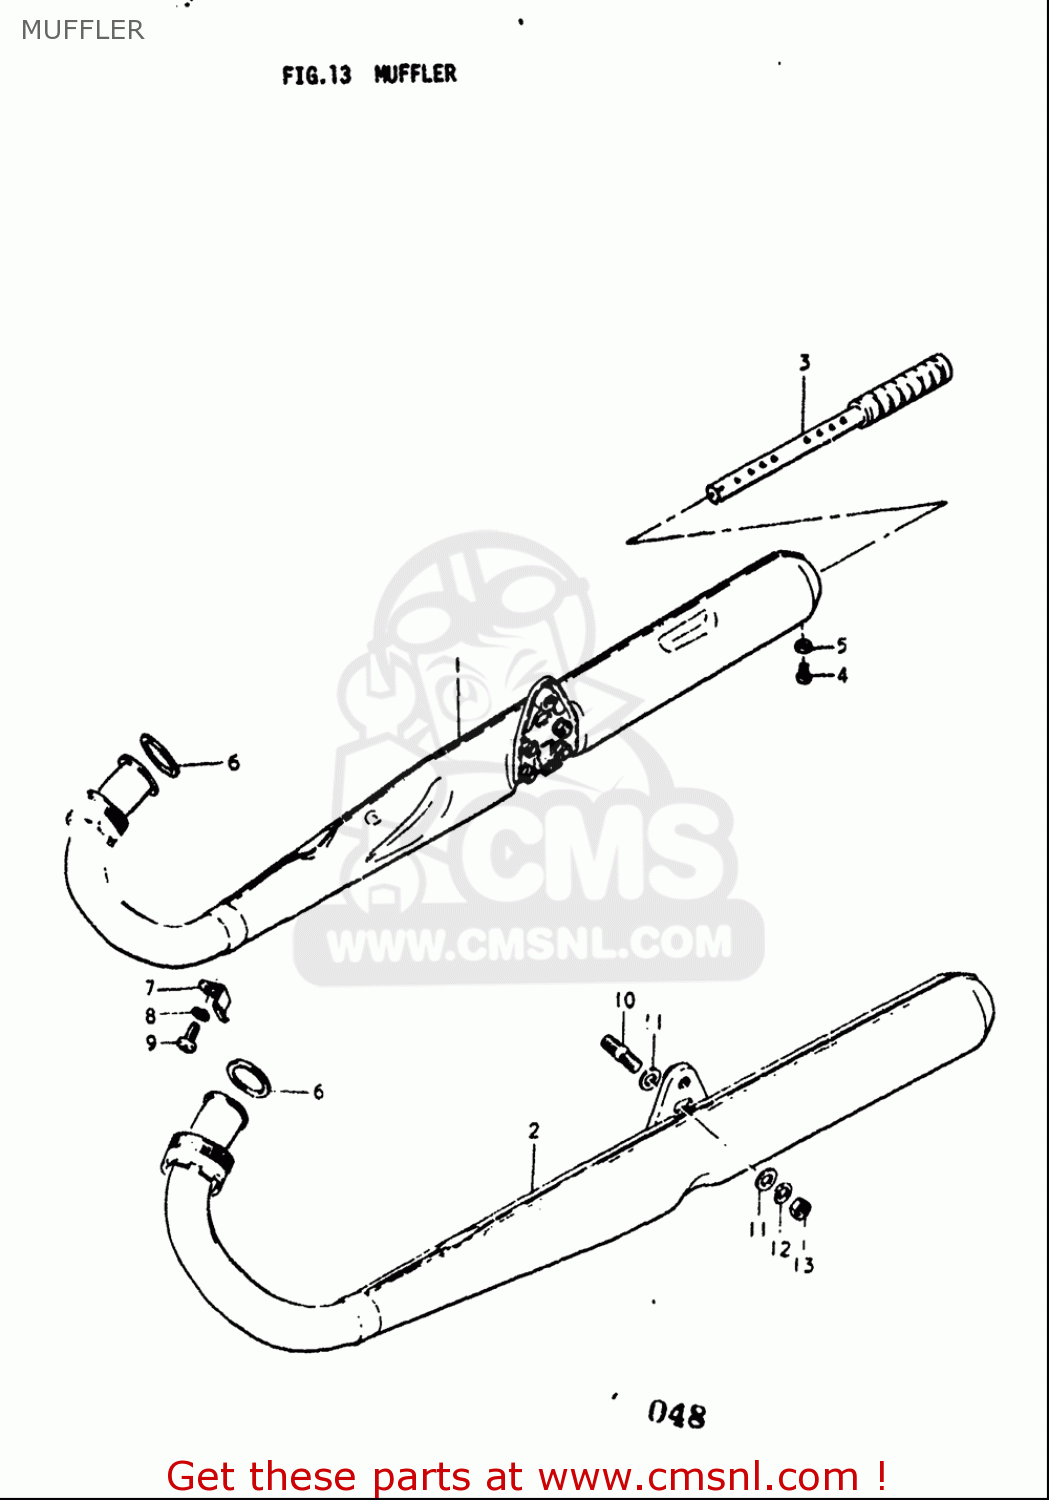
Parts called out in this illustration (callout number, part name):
3	PIPE,BAFFLE
4	BOLT(5X8)
5	WASHER,LOCK
6	GASKET,EXHAUST PIPE (NAS)
7	PLATE,EXHAUST PIPE
8	WASHER,LOCK
9	SCREW
11	WASHER
12	WASHER,LOCK
13	NUT
